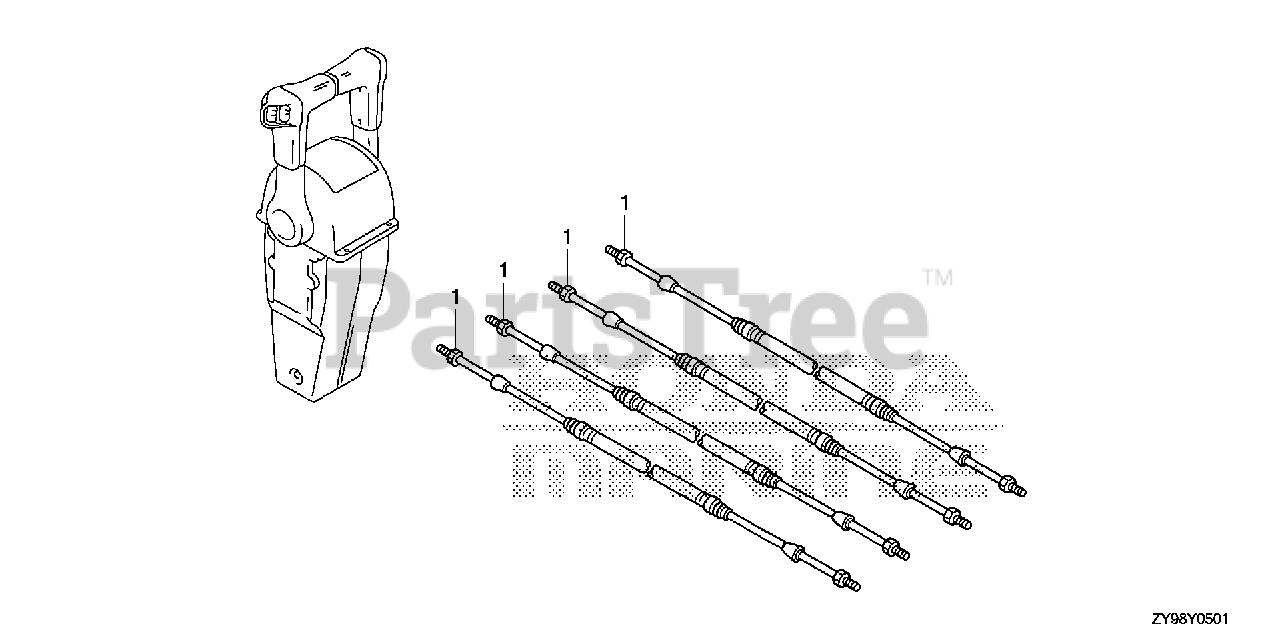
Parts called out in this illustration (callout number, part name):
1	CABLE, REMOTE CONTROL (10') (LOW FRICTION)
1	CABLE ASSY., PUSH-PULL (33C-5FT)
1	CABLE, REMOTE CONTROL (11') (LOW FRICTION)
1	CABLE ASSY., PUSH-PULL (33C-6FT)
1	CABLE, REMOTE CONTROL (12') (LOW FRICTION)
1	CABLE ASSY., PUSH-PULL (33C-7FT)
1	CABLE, REMOTE CONTROL (13') (LOW FRICTION)
1	CABLE ASSY., PUSH-PULL (33C-8FT)
1	CABLE, REMOTE CONTROL (14') (LOW FRICTION)
1	CABLE ASSY., PUSH-PULL (33C-9FT)
1	CABLE, REMOTE CONTROL (15') (LOW FRICTION)
1	CABLE ASSY., PUSH-PULL (33C-10FT)
1	CABLE, REMOTE CONTROL (16') (LOW FRICTION) (NOT AVAILABLE)
1	CABLE ASSY., PUSH-PULL (33C-11FT)
1	CABLE, REMOTE CONTROL (17') (LOW FRICTION)
1	CABLE ASSY., PUSH-PULL (33C-12FT)
1	CABLE, REMOTE CONTROL (18') (LOW FRICTION) (NOT AVAILABLE)
1	CABLE ASSY., PUSH-PULL (33C-13FT)
1	CABLE, REMOTE CONTROL (19') (LOW FRICTION)
1	CABLE ASSY., PUSH-PULL (33C-14FT)
1	CABLE, REMOTE CONTROL (20') (LOW FRICTION) (NOT AVAILABLE)
1	CABLE ASSY., PUSH-PULL (33C-15FT)
1	CABLE, REMOTE CONTROL (21') (LOW FRICTION)
1	CABLE ASSY., PUSH-PULL (33C-16FT)
1	CABLE, REMOTE CONTROL (22') (LOW FRICTION) (NOT AVAILABLE)
1	CABLE ASSY., PUSH-PULL (33C-17FT)
1	CABLE, REMOTE CONTROL (23') (LOW FRICTION)
1	CABLE ASSY., PUSH-PULL (33C-18FT)
1	CABLE, REMOTE CONTROL (24') (LOW FRICTION) (NOT AVAILABLE)
1	CABLE ASSY., PUSH-PULL (33C-19FT)
1	CABLE, REMOTE CONTROL (25') (LOW FRICTION)
1	CABLE ASSY., PUSH-PULL (33C-20FT)
1	CABLE, REMOTE CONTROL (26') (LOW FRICTION)
1	CABLE ASSY., PUSH-PULL (33C-21FT)
1	CABLE, REMOTE CONTROL (27') (LOW FRICTION)
1	CABLE ASSY., PUSH-PULL (33C-22FT)
1	CABLE, REMOTE CONTROL (28') (LOW FRICTION) (NOT AVAILABLE)
1	CABLE ASSY., PUSH-PULL (33C-23FT)
1	CABLE, REMOTE CONTROL (29') (LOW FRICTION)
1	CABLE ASSY., PUSH-PULL (33C-24FT)
1	CABLE, REMOTE CONTROL (30') (LOW FRICTION) (NOT AVAILABLE)
1	CABLE ASSY., PUSH-PULL (33C-25FT)
1	CABLE, REMOTE CONTROL (31') (LOW FRICTION)
1	CABLE ASSY., PUSH-PULL (33C-26FT)
1	CABLE, REMOTE CONTROL (32') (LOW FRICTION) (NOT AVAILABLE)
1	CABLE ASSY., PUSH-PULL (33C-27FT)
1	CABLE, REMOTE CONTROL (33') (LOW FRICTION)
1	CABLE ASSY., PUSH-PULL (33C-28FT)
1	CABLE, REMOTE CONTROL (34') (LOW FRICTION) (NOT AVAILABLE)
1	CABLE ASSY., PUSH-PULL (33C-29FT)
1	CABLE, REMOTE CONTROL (35') (LOW FRICTION)
1	CABLE ASSY., PUSH-PULL (33C-30FT)
1	CABLE ASSY., PUSH-PULL (33C-31FT)
1	CABLE ASSY., PUSH-PULL (33C-32FT)
